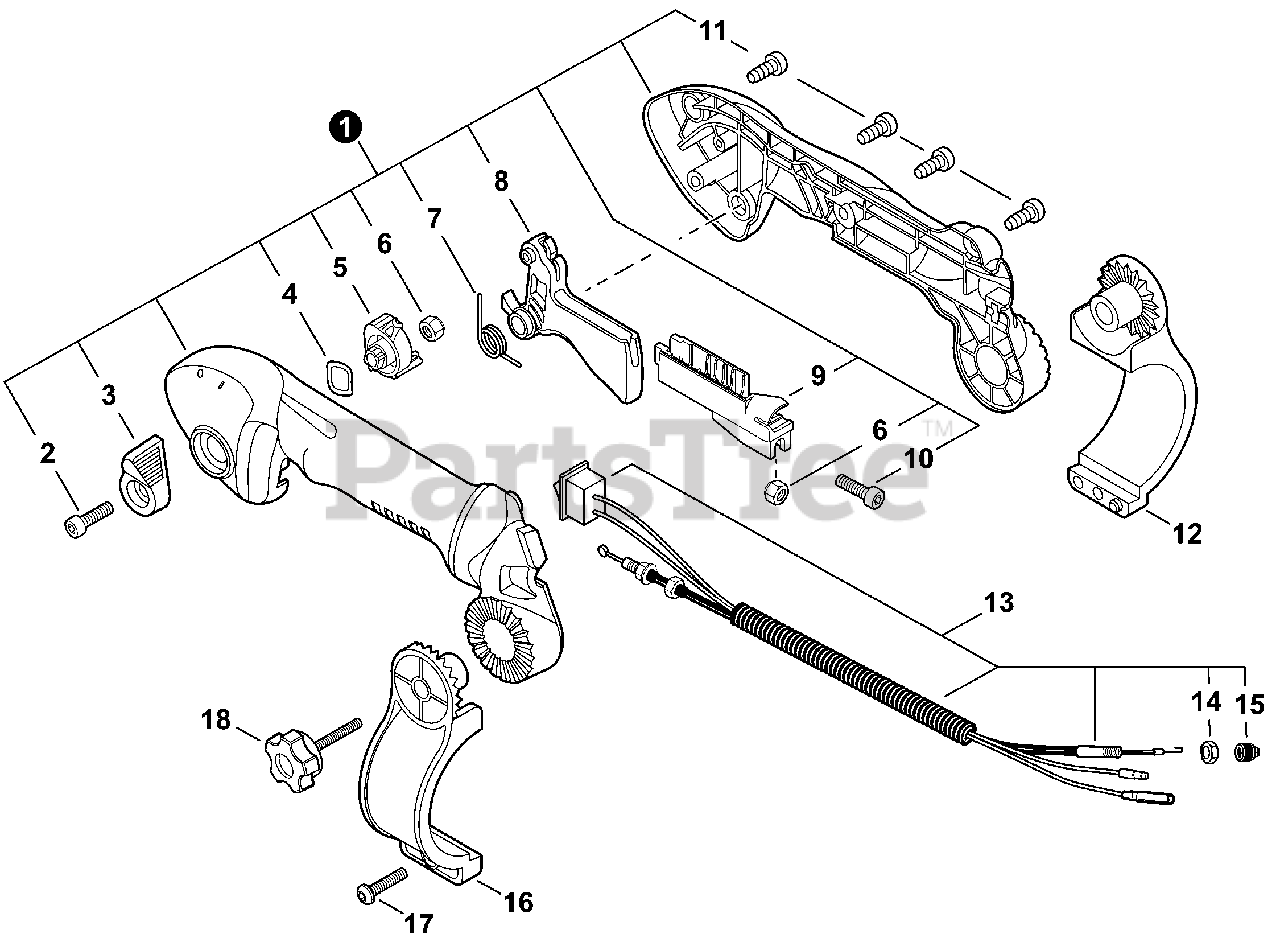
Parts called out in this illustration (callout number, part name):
1	THROTTLE CONTROL KIT - TUBE MOUNT
2	BOLT, TORX 5×20
3	LEVER, THROTTLE
4	WASHER, WAVE 12
5	CONTROL, THROTTLE
6	NUT, LOCK M5
7	SPRING, TORSION
8	TRIGGER, THROTTLE
9	CONNECTOR, CABLE
10	BOLT, TORX 5×30
11	BOLT, TORX 5×16
12	BRACKET, HANDLE - RIGHT
13	CABLE ASSY, CONTROL
14	NUT, HEX M6
15	CAP, DUST
16	BRACKET, HANDLE - LEFT
17	BOLT, TORX 5×20
18	KNOB, SCREW M6×50MM
